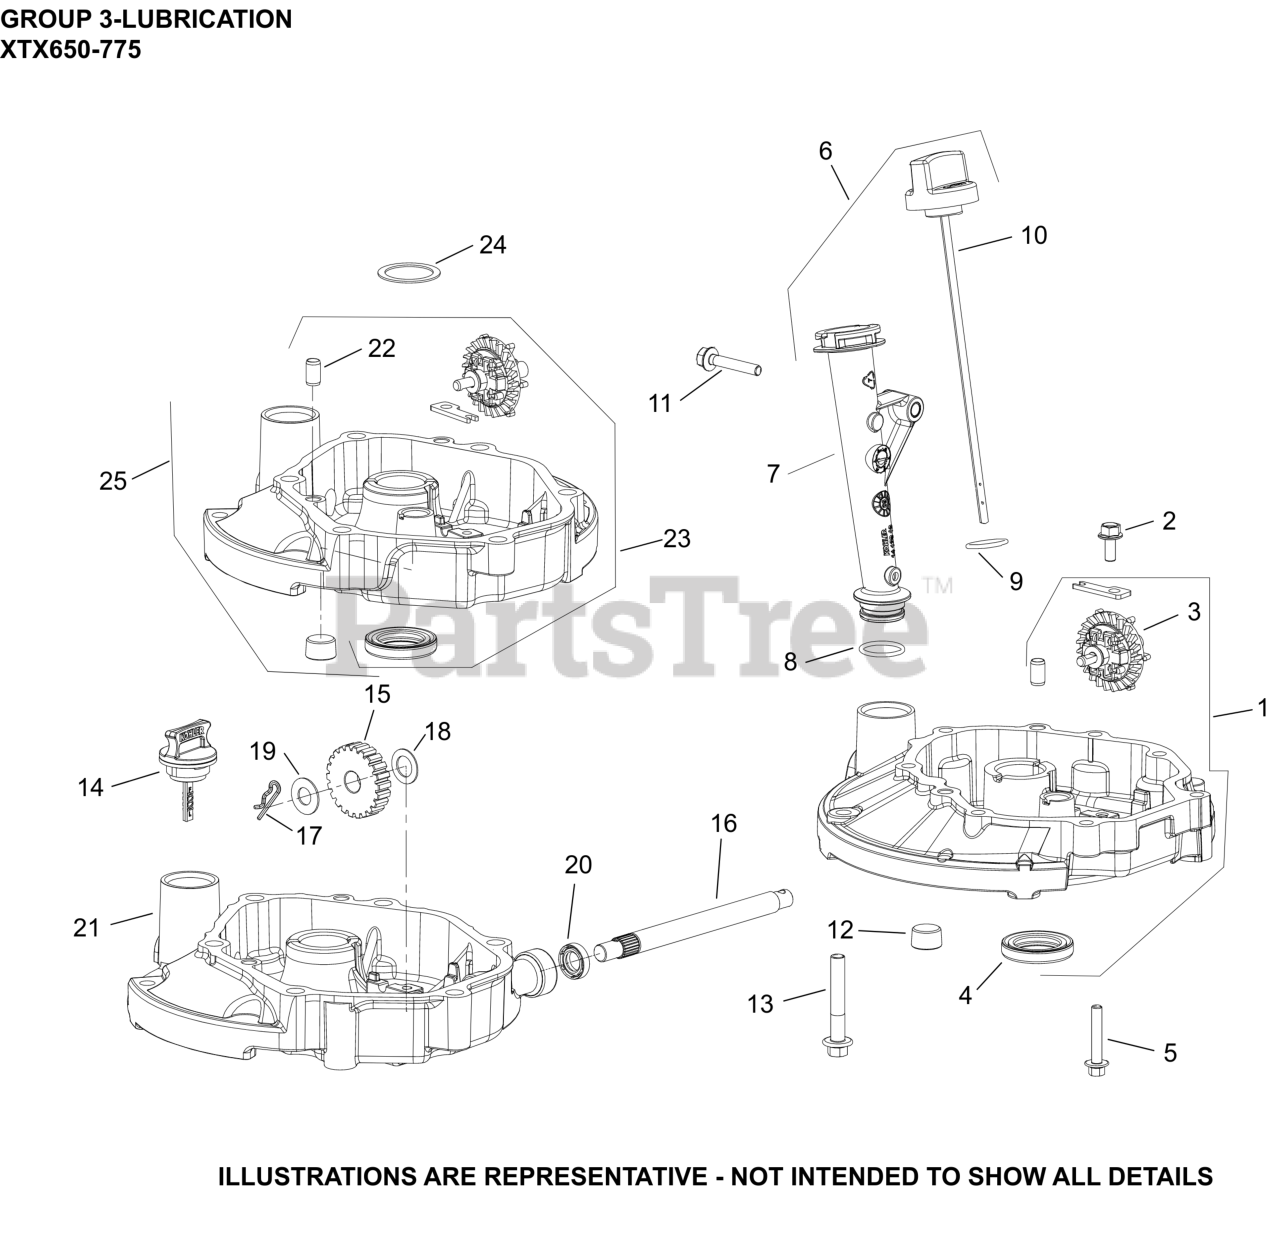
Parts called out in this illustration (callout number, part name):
1	KIT, OIL PAN
3	GEAR ASSEMBLY, GOVERNOR
5	SCREW, HEX FLANGE (M6)-(#25086434S)
14	DIPSTICK ASSEMBLY
22	PIN, DOWEL (8mm)
24	WASHER, THRUST
